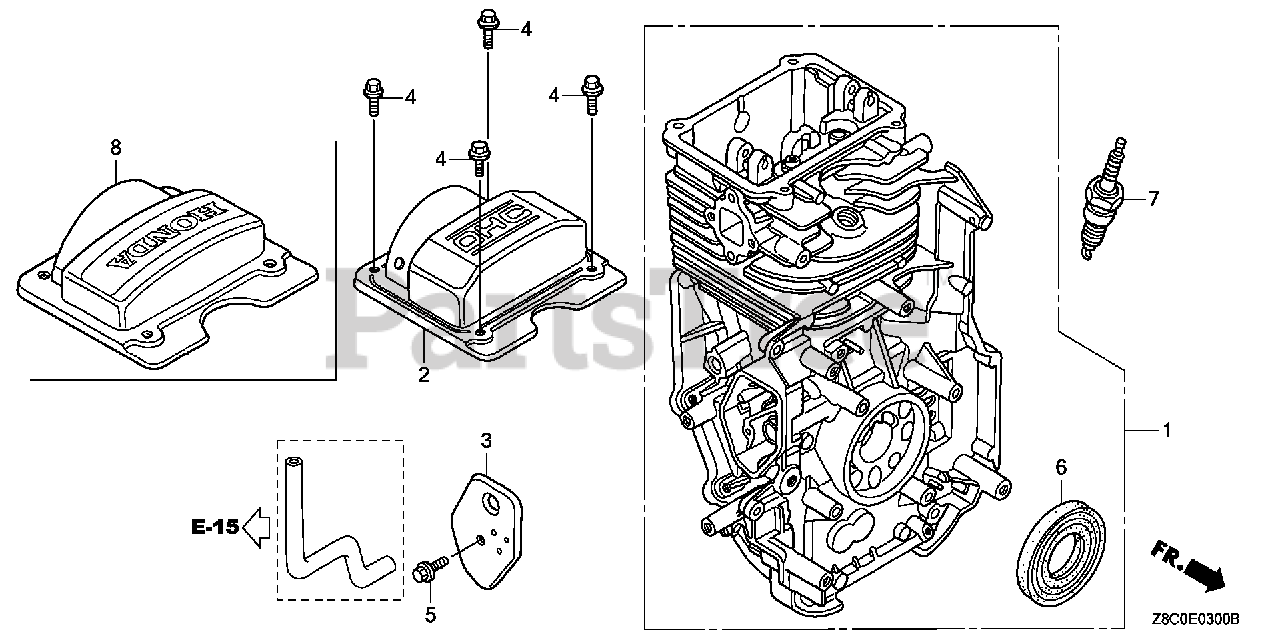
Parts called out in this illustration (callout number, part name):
1	CYLINDER ASSY.
2	COVER, CYLINDER HEAD
3	COVER, BREATHER (Honda Code 5580006). (BREATHER VALVE ASSY.)
4	BOLT, FLANGE (6X12) (CT200)
5	BOLT, FLANGE (6X14)
6	OIL SEAL (25.4X62X6)
7	SPARK PLUG (BPR6ES) (NGK)
8	COVER, CYLINDER HEAD
